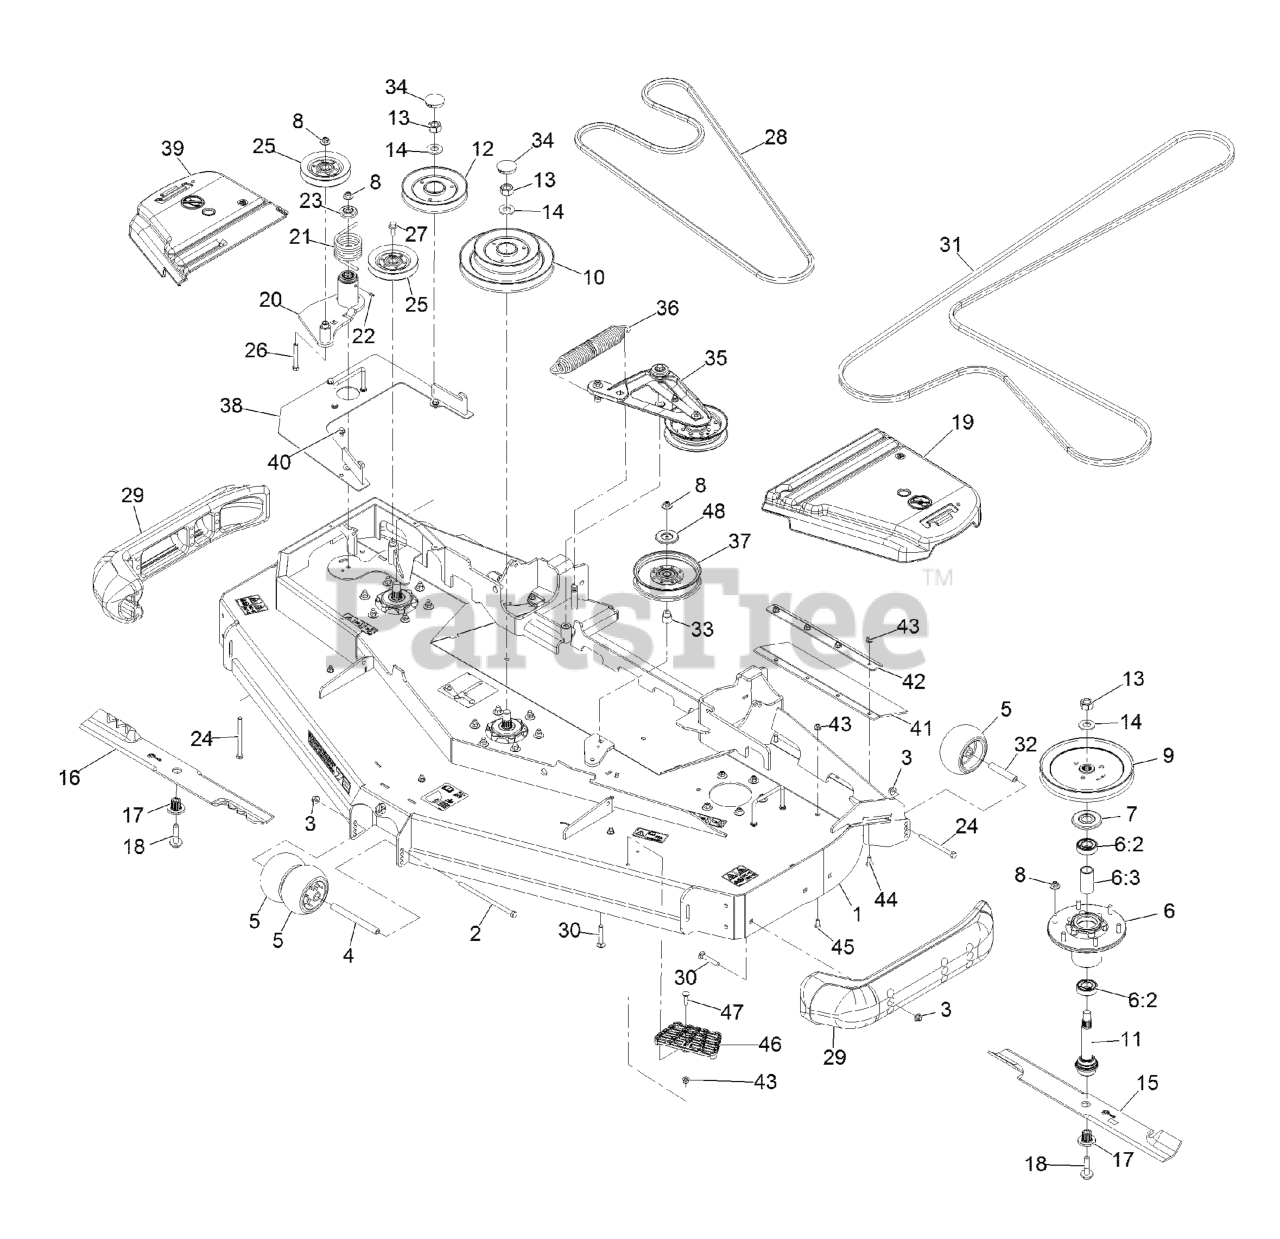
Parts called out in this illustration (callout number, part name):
1	DECK-RD72 NLZ, W/DECALS
2	SCREW-HH
3	NUT-HF, NI
4	SPACER-WHEEL
5	ROLLER-SCALP, ANTI
6	ASM-CUTTER HSG WITH BEARINGS
6:2	BEARING-BALL
6:3	SPACER-BEARING
7	GUARD,BEARING TOP .989
8	Nut-Nyloc 3/8-16 Flg
9	SHEAVE,BLADE DRIVE 8.74
10	SHEAVE, DOUBLE 72RD
11	ASM-SPINDLE AND SEAL
12	SHEAVE-RD REV DRIVE SERIES 4
13	NUT-HEX
17	BUSHING,SPLINED
18	SCREW,SEMS 1/2-20 X 2.19
19	COVER-BELT, LH
20	IDLER ASM
21	SPRING-TORSION
22	FITTING-GREASE
23	GUARD-TOP
24	SCREW-HH
26	SCREW-HH
27	SCREW-HHF
29	SKID-BUMPER, DECK
30	Bolt-Carriage 3/8-16 X 2 1/4
32	TUBE-SPANNER
33	BUSHING-IDLER
34	PLUG,BLACK NYLON 1.75
35	DECK IDLER ASM
36	SPRING-EXTENSION
37	IDLER-PULLEY, FLAT 6.00X1.00
38	COVER-REVERSE DRIVE
39	COVER-BELT, RH
41	GUARD-TIRE
42	SUPPORT-OUTER FLAP
43	NUT-HF, NI
44	SCREW-CARR
45	SCREW-HSBH
46	STEP-DECK
47	Bolt-Carriage 5/16-18 X 1 1/4
48	SHIELD-DUST
